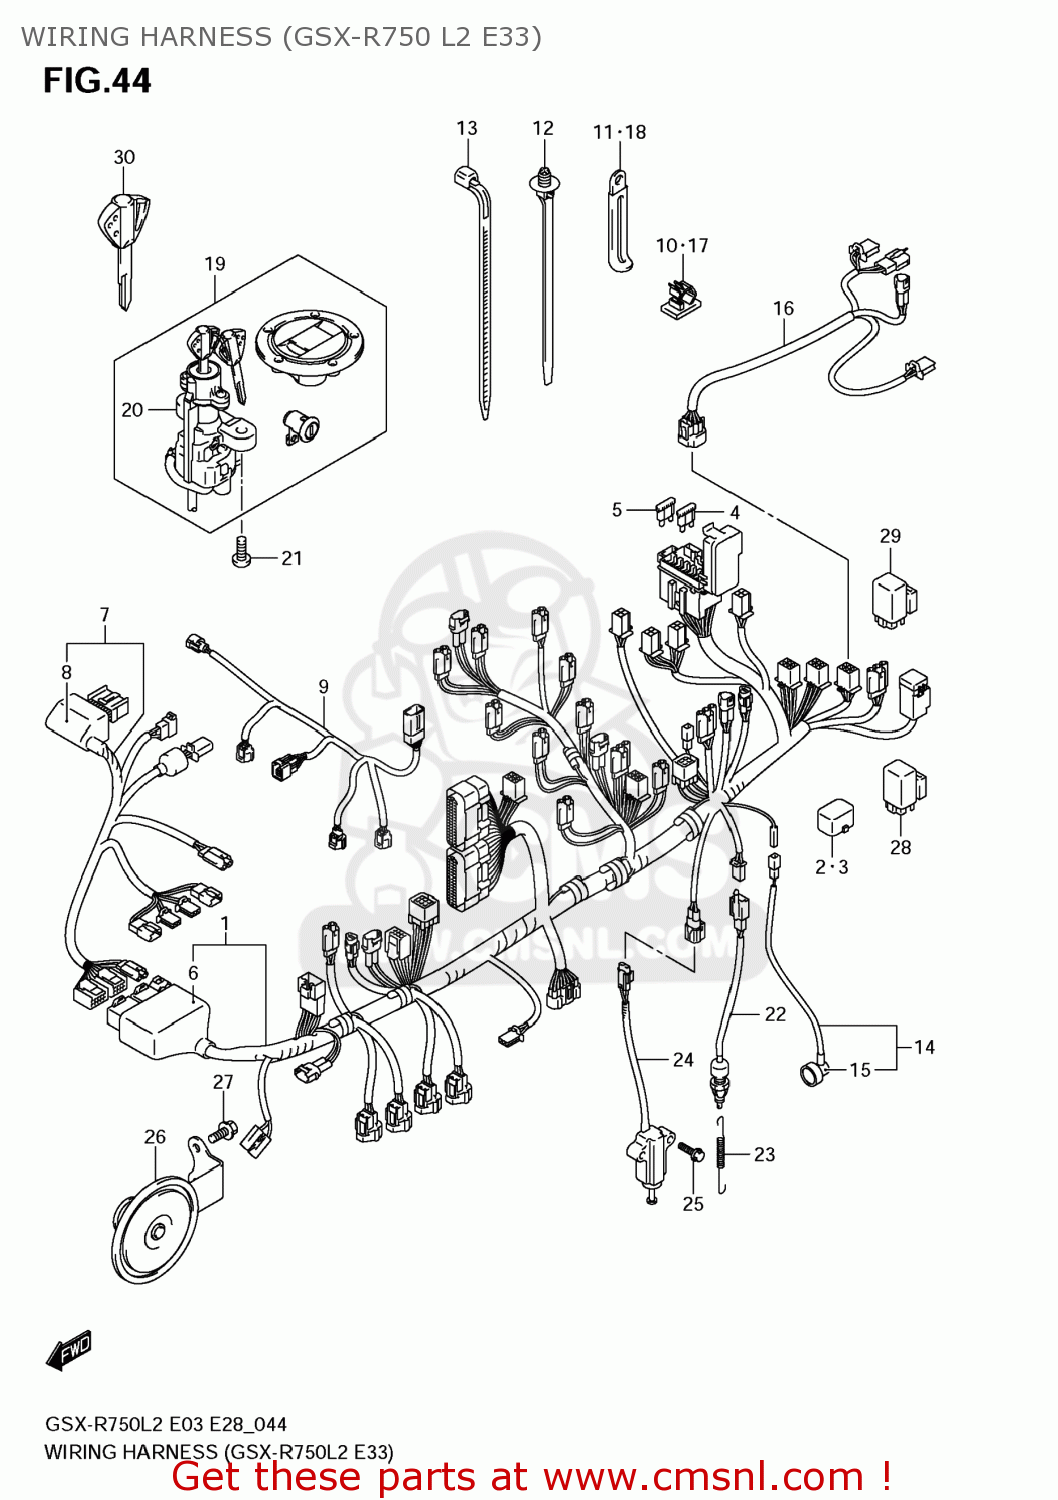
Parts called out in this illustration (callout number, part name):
1	HARNESS,WIRING NO.1
2	CAP,TS
3	CAP,CO ADJUST
4	FUSE(10A)
5	FUSE(15A)
6	COVER
7	HARNESS,WIRING NO.2
8	COVER,CONNECTOR
9	HARNESS,WIRING NO.3
10	CLAMP(L:95)
11	CLAMP(L:145)
12	CLAMP(L:154)
13	CLAMP(L:125)
14	WIRE,OIL PRESSURE SWITCH LEAD
15	CAP,OIL PRESSURE SWITCH
16	WIRE,RR COMB LEAD
17	CLAMP
18	CLAMP(L:45)
19	LOCK SET
20	LOCK ASSY,STEERING
21	BOLT(8X20)
22	SWITCH ASSY,STOP LAMP
23	SPRING
24	SWITCH ASSY,SIDE STAND
25	BOLT
26	HORN ASSY
27	BOLT
28	RELAY ASSY
29	RELAY ASSY
30	KEY,BLANK(IMMOBII)
